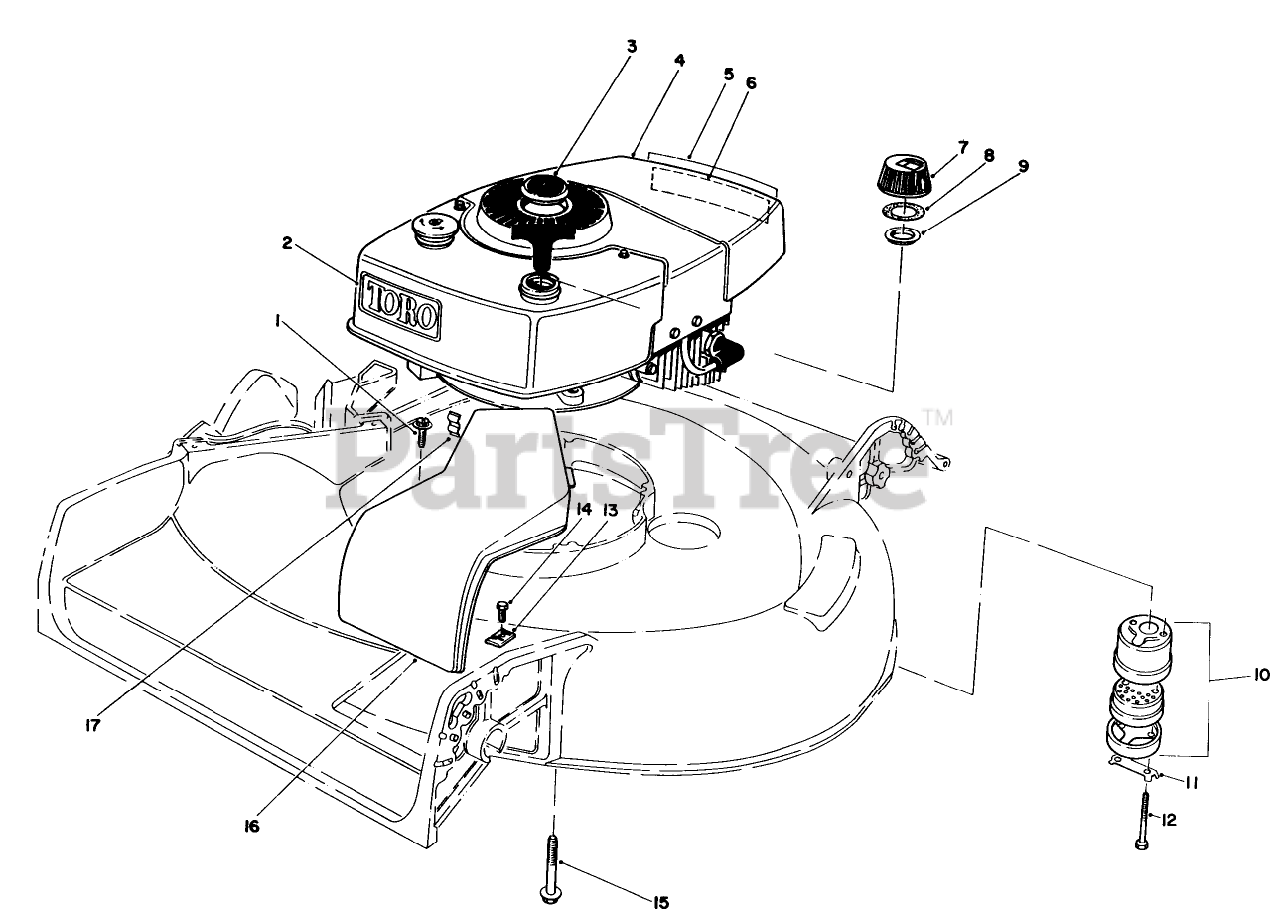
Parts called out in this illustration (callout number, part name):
1	Screw-Thread Forming
4	Engine
8	GASKET
10	MUFFLER ASM
11	CLIP - LOCKING
12	SCREW-HH
14	SCREW-THD ROLL, HWH
15	3/8-16 X 2-3/4 CAPSCR
